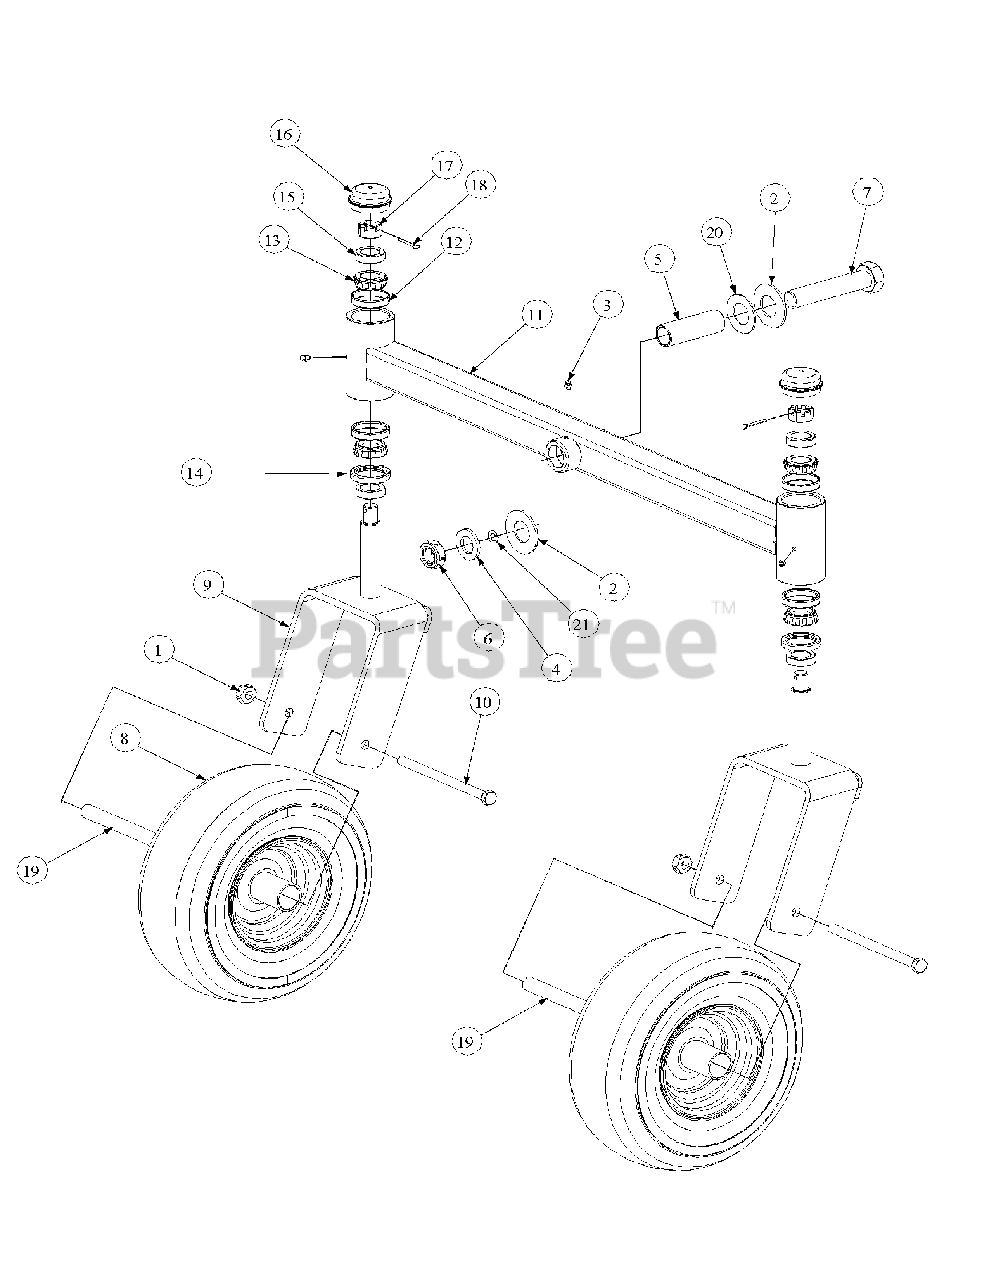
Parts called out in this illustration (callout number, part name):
1	Nut, 1/2-20, Center Lock
2	Bell Washer, 1.25 ID
3	Grease Fitting
4	Special Washer
5	Spacer, 1.005 ID x 1.25 OD x 3.6
6	Nut, Jam, 1.0-14, Insert Lock
7	Hex Cap Screw, 1-14 x 5.0
8	Wheel, 13 x 5-6, White: Includes;
8	Front Roller Bearings
8	Front Retainer Bushings
9	Yoke, Caster Wheel
10	HHCS, 1/2-20, 7.00
11	Straight Front Axle
12	Cup Bearing
13	Bearing Cone
14	Seal
15	Ring Seal
16	Grease Cap, 1.986 OD
17	Slotted Nut, 3/4-16
18	Cotter Pin, 5/32, 1.25
19	Wheel Spacer
20	Flat Washer, 1.25 ID
21	Washer
